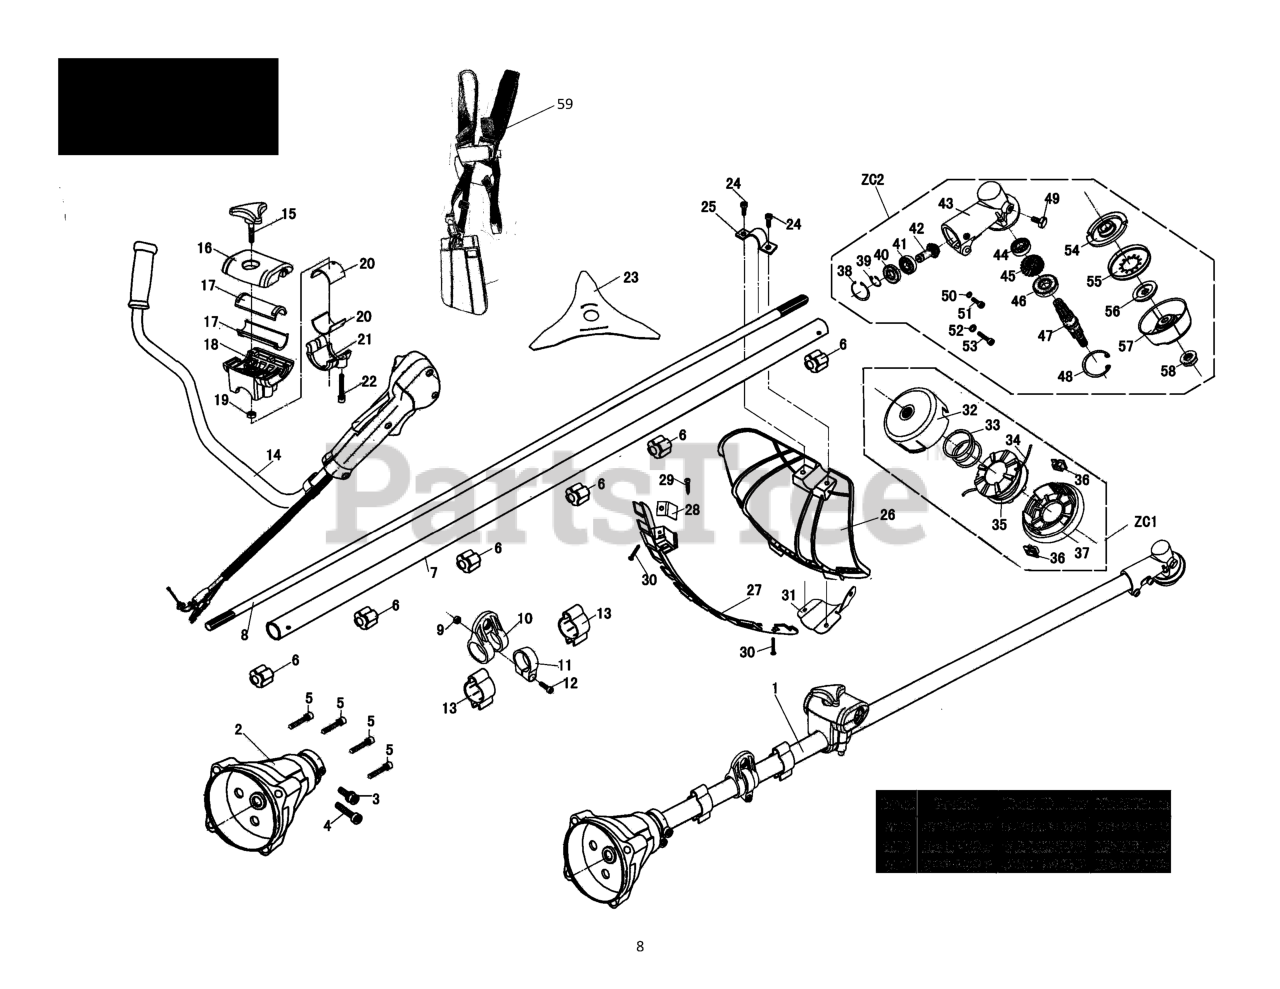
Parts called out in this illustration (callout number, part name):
2	Output based
4	COMBINATION SCREW
5	Combination screw
6	Oil bearing
8	DRIVE SHAFT
11	HOOK FIX SEAT
13	F28 pipe cli
14	switch assy
15	knob of Pressing plate
16	Upper press plate
18	middle press plate
21	down press plate
22	Combination screw
25	Pressing plate of protector
26	3G Protector
27	Protector plate(black )
28	Small blade
29	Tapping screw
30	Tapping screw
31	Under plate of protector
32	NYLON HEAD COVER ASSY
33	Return spring
34	Nylon rope
35	String shaft
36	Sheath of nylon head
37	Nylon head base
38	RING SNAP
39	Retaining Ring For Shaft
40	Ball Bearing
41	Ball Bearing
42	Input Bevel Gear
43	Gear Box
44	BALL BEARING
45	Output Bevel Gear
46	Ball Bearing
47	Output Shaft
48	Ring snap
49	Hex bolt and flat washer assy
54	Shaft Bushing
55	Blade Holder
56	Gear box washer
57	Blade Holder Cover
58	Locking Nut: Cutting Blade
59	Belt, Double Harness
ZC1	Nylon head
ZC2	gearbox assy
